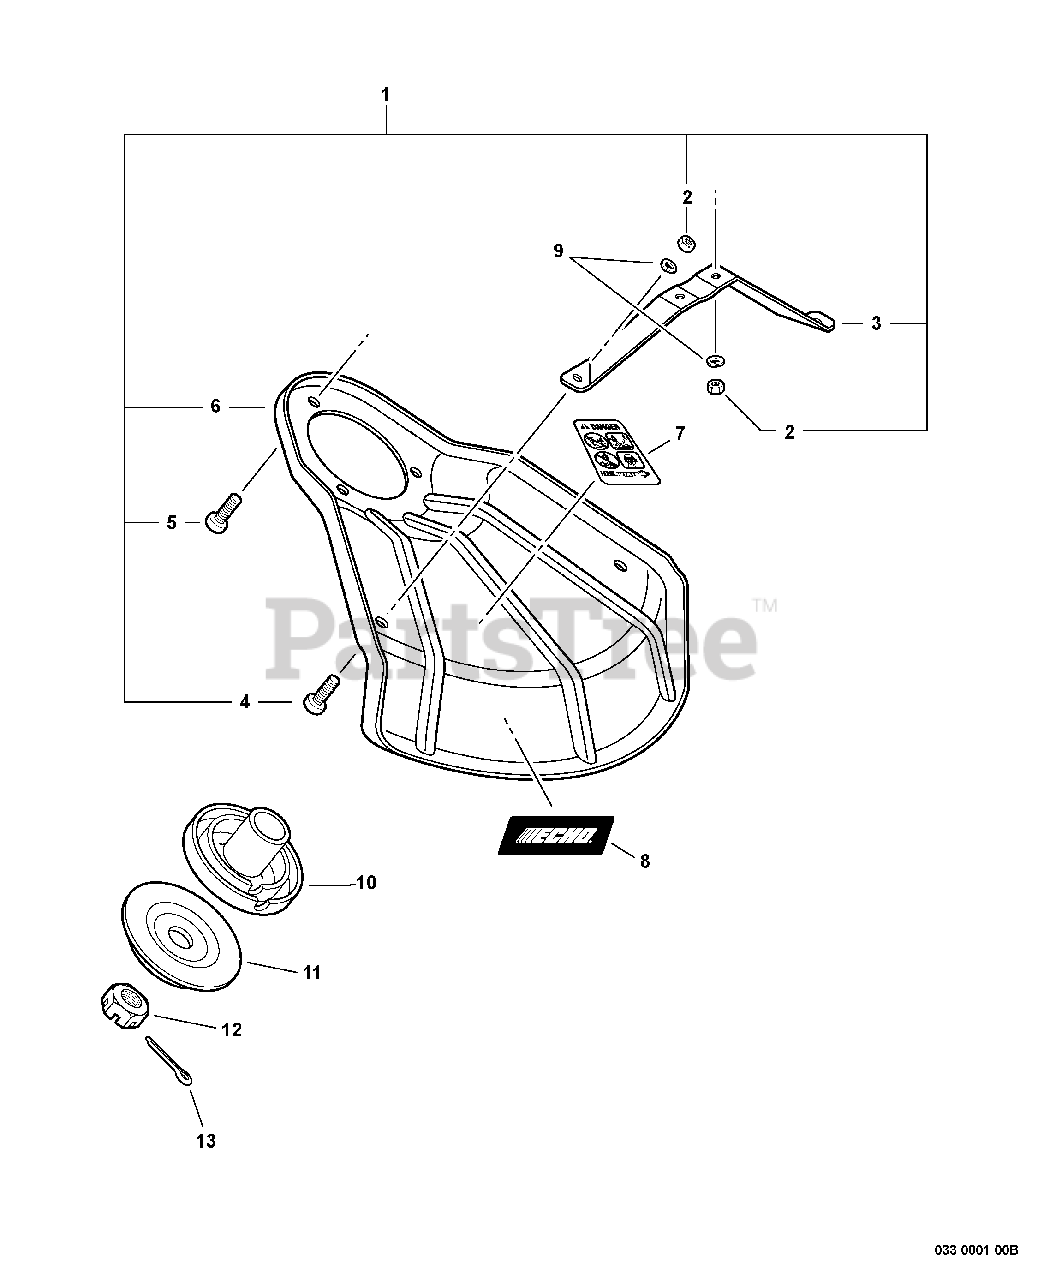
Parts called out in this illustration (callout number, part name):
1	DEBRIS SHIELD KIT
3	BRACKET, SHIELD
4	SCREW - 5X8
5	SCREW - 5X10
6	SHIELD, DEBRIS - METAL
7	LABEL - DANGER
8	LABEL - ECHO
9	LOCKWASHER - 5
10	ADAPTOR, BLADE - UPPER
11	ADAPTOR, BLADE - LOWER
12	NUT - 10 -- LEFT HAND
13	PIN, SPLIT - 2X22
